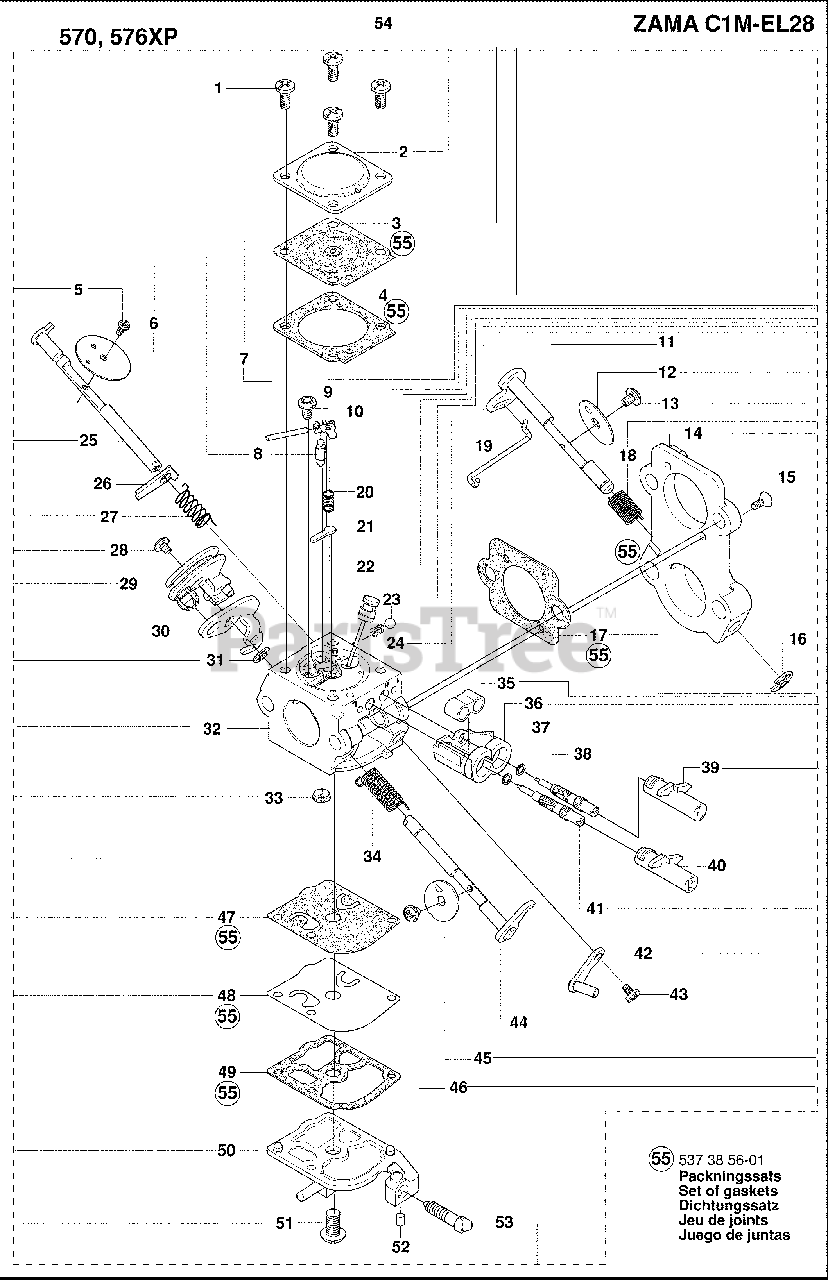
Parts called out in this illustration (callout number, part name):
6	CHOKE FLAP
7	Pin
8	Inlet Needle
12	THROTTLE FLAP
14	Carburetor
25	Choke Shaft
32	Carburetor
38	NEEDLE HIGH SPEED
41	LOW SPEED NEEDLE
44	Throttle Shaft
47	Pump Diaphragm
54	Carburetor
55	Gasket Set
